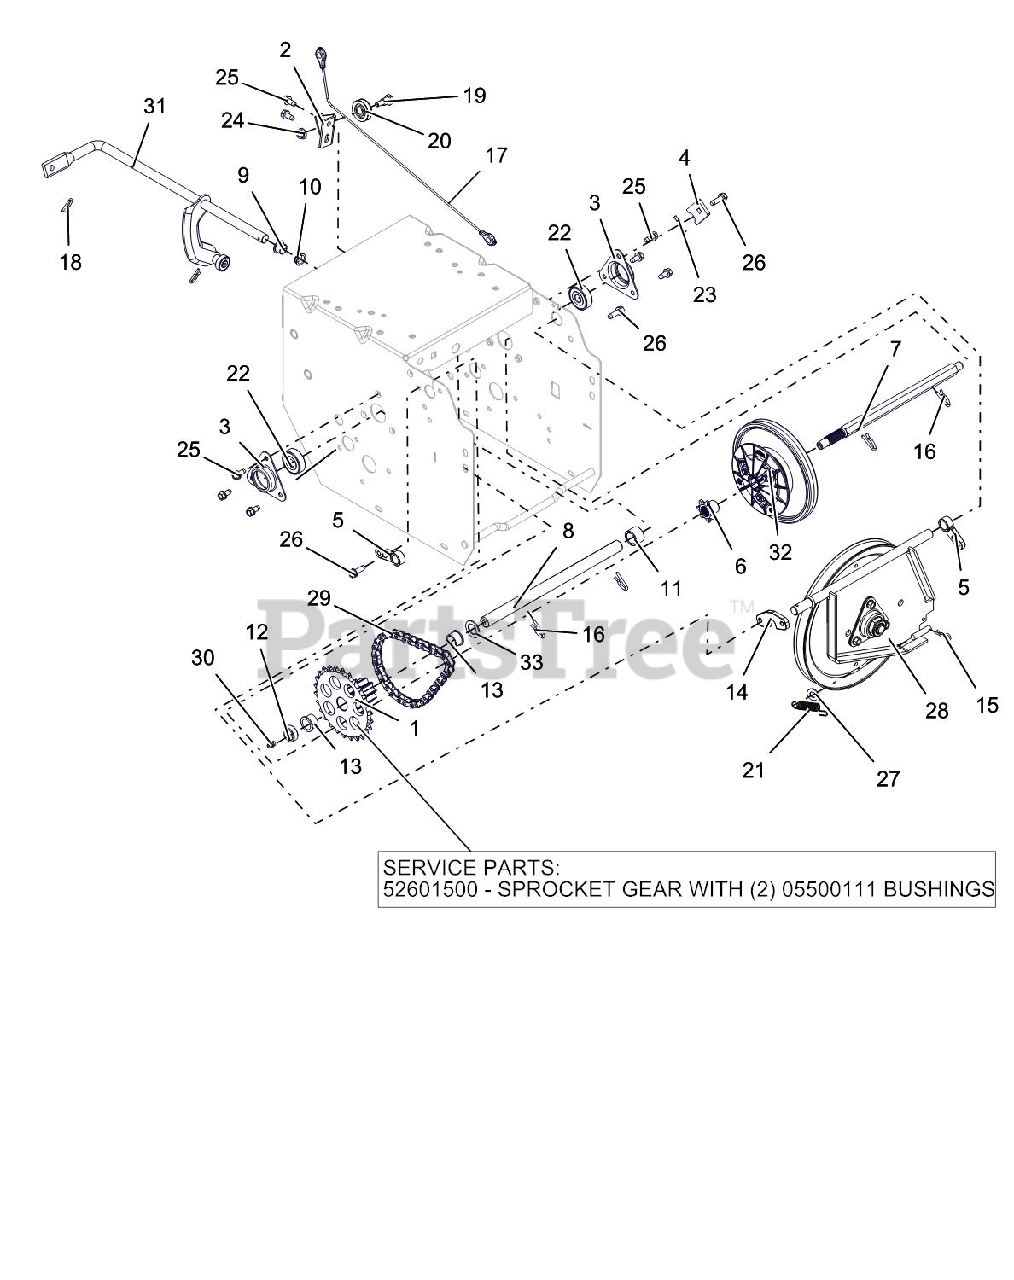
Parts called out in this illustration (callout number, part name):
1	PINION & SPROCKET
2	BRACKET, CABLE PULLEY
3	FLANGE, BEARING
4	TAB, ANTI ROTATION
5	SUPPORT BUSHING, SWING GATE
6	SPROCKET, PINION 7T W/SPLINE
7	SHAFT, HEX W/SPLINE TRACK
8	SHAFT, PINION TRACK
9	BUSHING, POLYLINER-.50 SPLIT
10	BUSHING, POLYLINER-.50 SNAPIN
11	SPACER, .635X.880X.611
12	BSHG-SLV, .635X.880X.305
13	BSHG-FLG .625X.750X.500X.875
13	PINION & SPROCKET W/BUSHINGS
14	SPACER, SWING GATE
15	PIN-HAIR INT .08X.18X1.18 YWZC
16	PIN, SPRING CLIP
17	CABLE, LOWER TRACTION (CMPCT)
18	CLIP, SPRING
19	BOLT, SHLDR-.375X.375X.25-20
20	PULLEY, CABLE
21	SPRING, EXT. .043X.438X1.64
22	BRG-BALL .437X1.375X.437
23	@PIN-GRV .125X1.00 TP E ALLOY
24	@NUT-LK-CTR-FLG .25-20 YWZC
25	SCR-TAP .25-20X.50 HWH TR YWZ
26	SCR-TAP-PM .25-20X.75 TR YWZ
27	@WSHR-FL-STL.344X.688X.065YWZC
28	PLATE, SWING - ASSEMBLY
29	CHAIN - #41, 32 PITCHES
30	ZERK,FITTING .25X.125 DRIVE IN
31	ARM, SHIFT-SMALL DASH (WLDMT)
32	DISC, FRICTION DRIVE-ASSEMBLY
33	WSHR-FL-STL .630X1.005X.062 YZ
